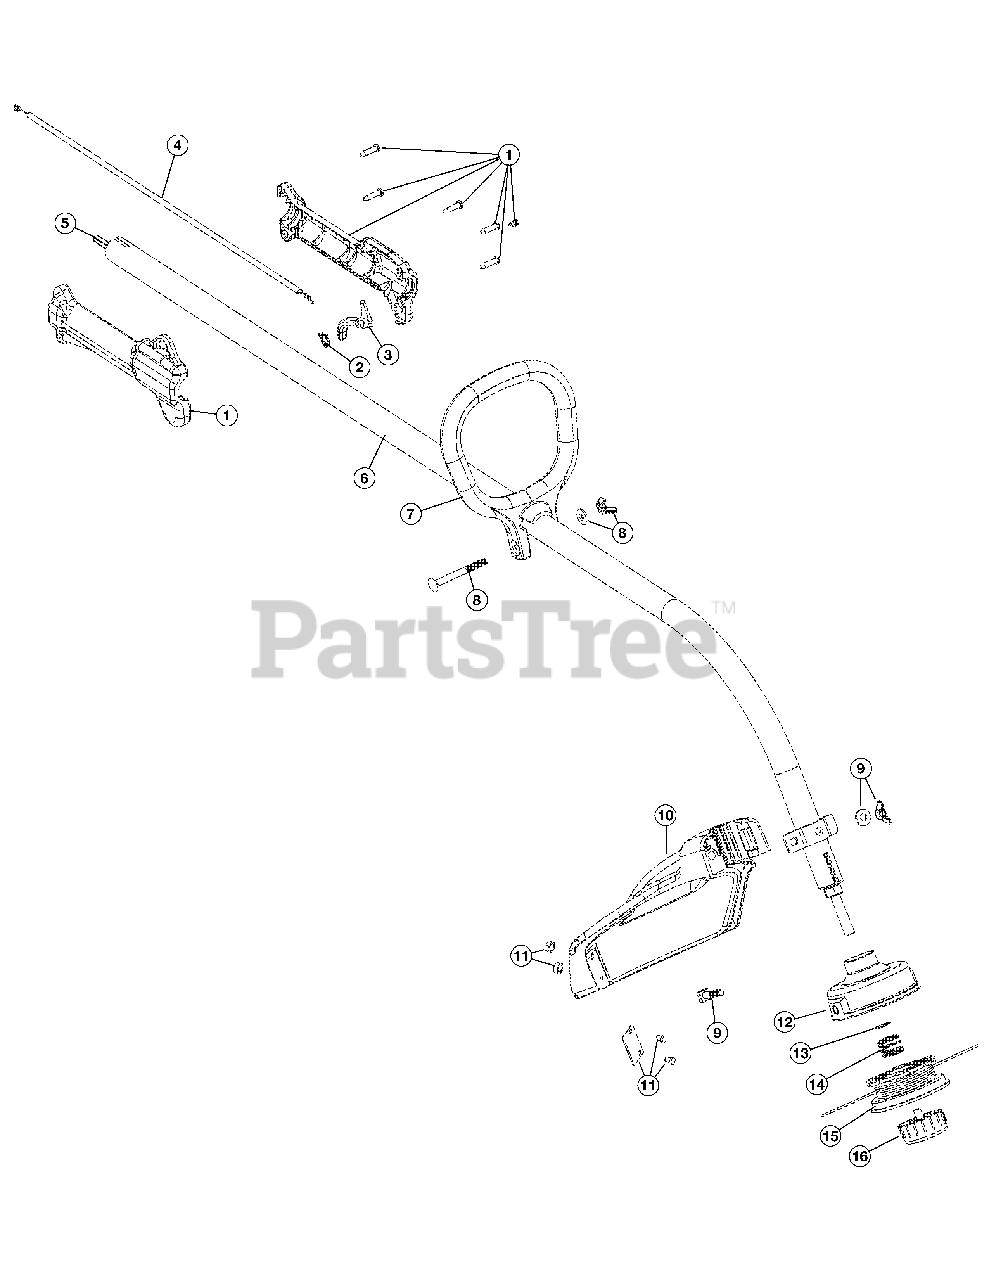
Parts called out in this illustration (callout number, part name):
1	Throttle Housing Assembly (includes 2 & 3)
2	Throttle Trigger Spring
3	Throttle Trigger
4	Throttle Cable
5	Flexible Drive Shaft
6	Drive Shaft Housing (includes 5 & 13)
7	D-Handle Assembly (includes 8)
8	D-Handle Hardware
9	Guard Mounting Hardware
10	Guard (includes 11)
11	Blade Assembly
12	Outer Reel (includes 13)
13	Retainer
15	Inner Reel (line not included)
16	Bump Knob
